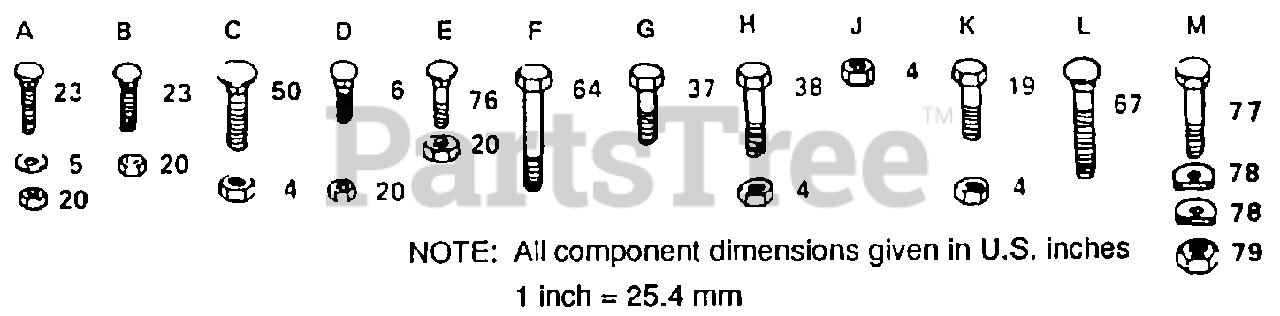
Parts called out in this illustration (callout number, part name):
5	WASHER M
6	BOLT
23	BOLT
37	SCREW
38	SCREW
50	BOLT
64	BOLT
67	BOLT.3/8-14X1.25
77	BOLT LT
78	WASHER T
